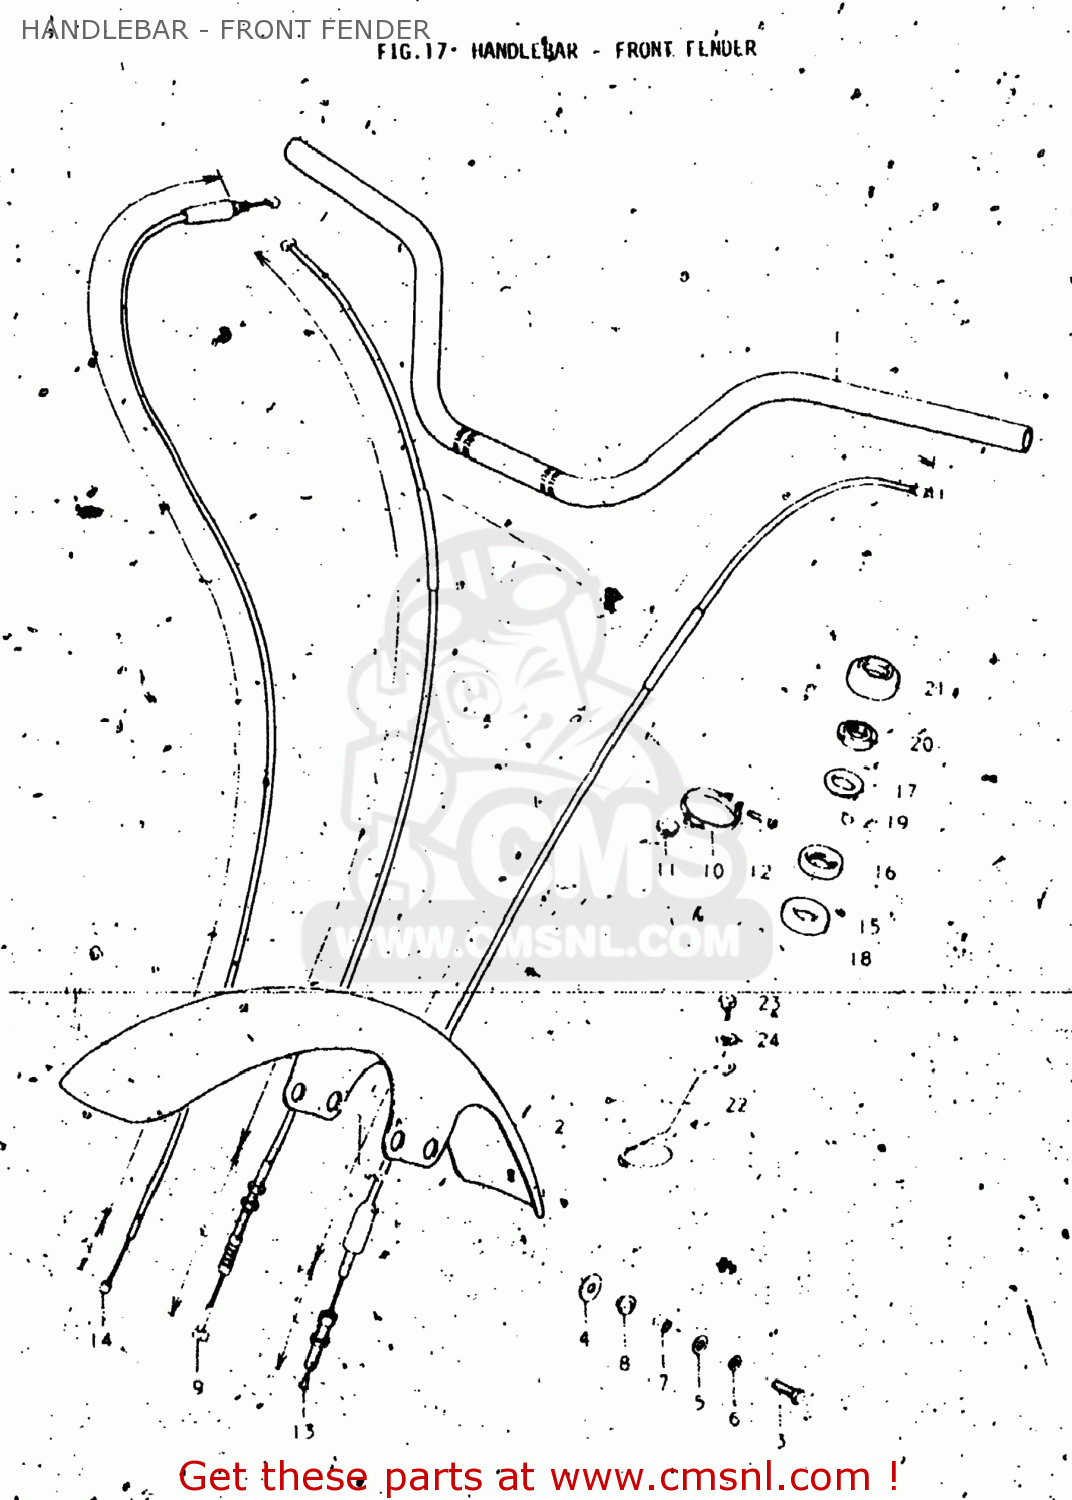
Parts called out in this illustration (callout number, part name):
1	HANDLEBAR,RIGHT
2	FENDER,FRONT
3	BOLT
4	WASHER (6.5X29X1.6)
5	WASHER (6.5X20X1.2)
6	LOCK WASHER
7	SPACER
8	CUSHION
9	CABLE,FRONT BRAKE
10	GUIDE,CABLE
11	CUSHION
12	SCREW
13	CABLE ASSEMBLY,CLUTCH
14	CABLE ASSY,THROTTLE
15	LACE,STEERING INNER LWR
16	RACE,STEERING INNER UPR
17	RACE,STEERING OUTER UPR
18	BALL
19	BALL
20	NUT,STEERING STEM(25X44X10)
21	DUST SEAL,STEERING UPR
22	GUIDE,CABLE
23	BOLT
24	LOCK WASHER
